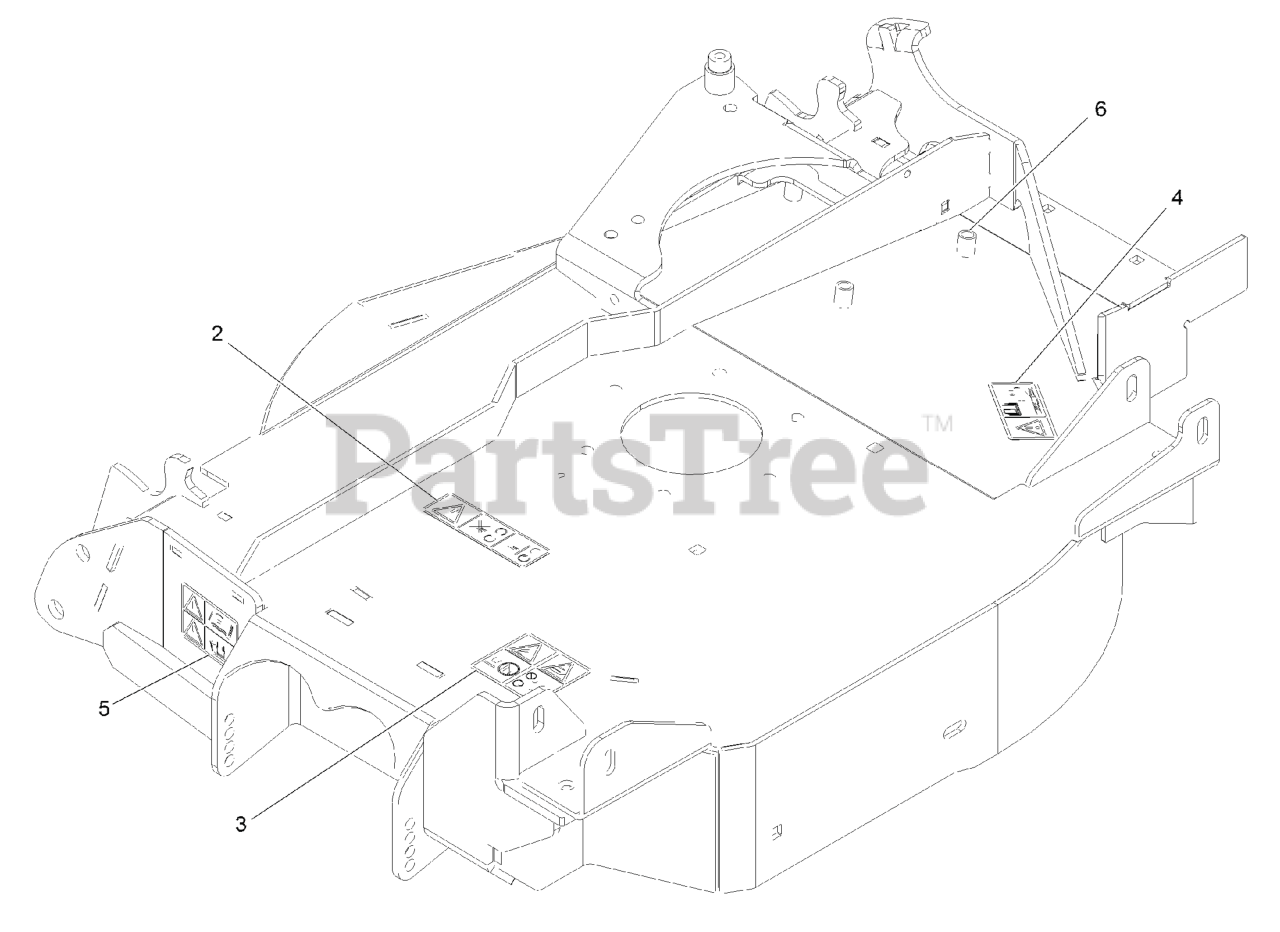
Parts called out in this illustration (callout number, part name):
2	DECAL-COVER, MISSING
3	DECAL-DANGER, THROWN OBJECT
4	DECAL-TORQUE, BOLT
5	DECAL-WARNING, PINCH POIN
6	NUT-CLINCH
